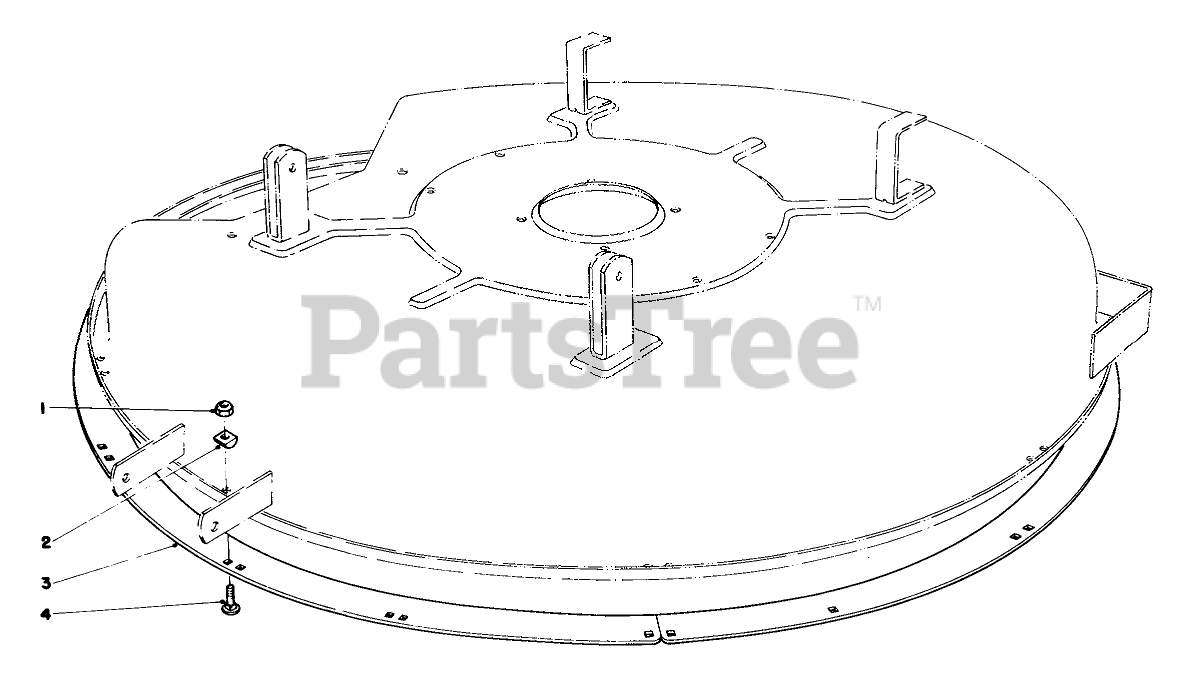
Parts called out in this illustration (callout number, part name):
1	NUT-LOCK, NI
2	Spacer-Deck Ring
3	DECK RING B
4	BOLT-CARR
